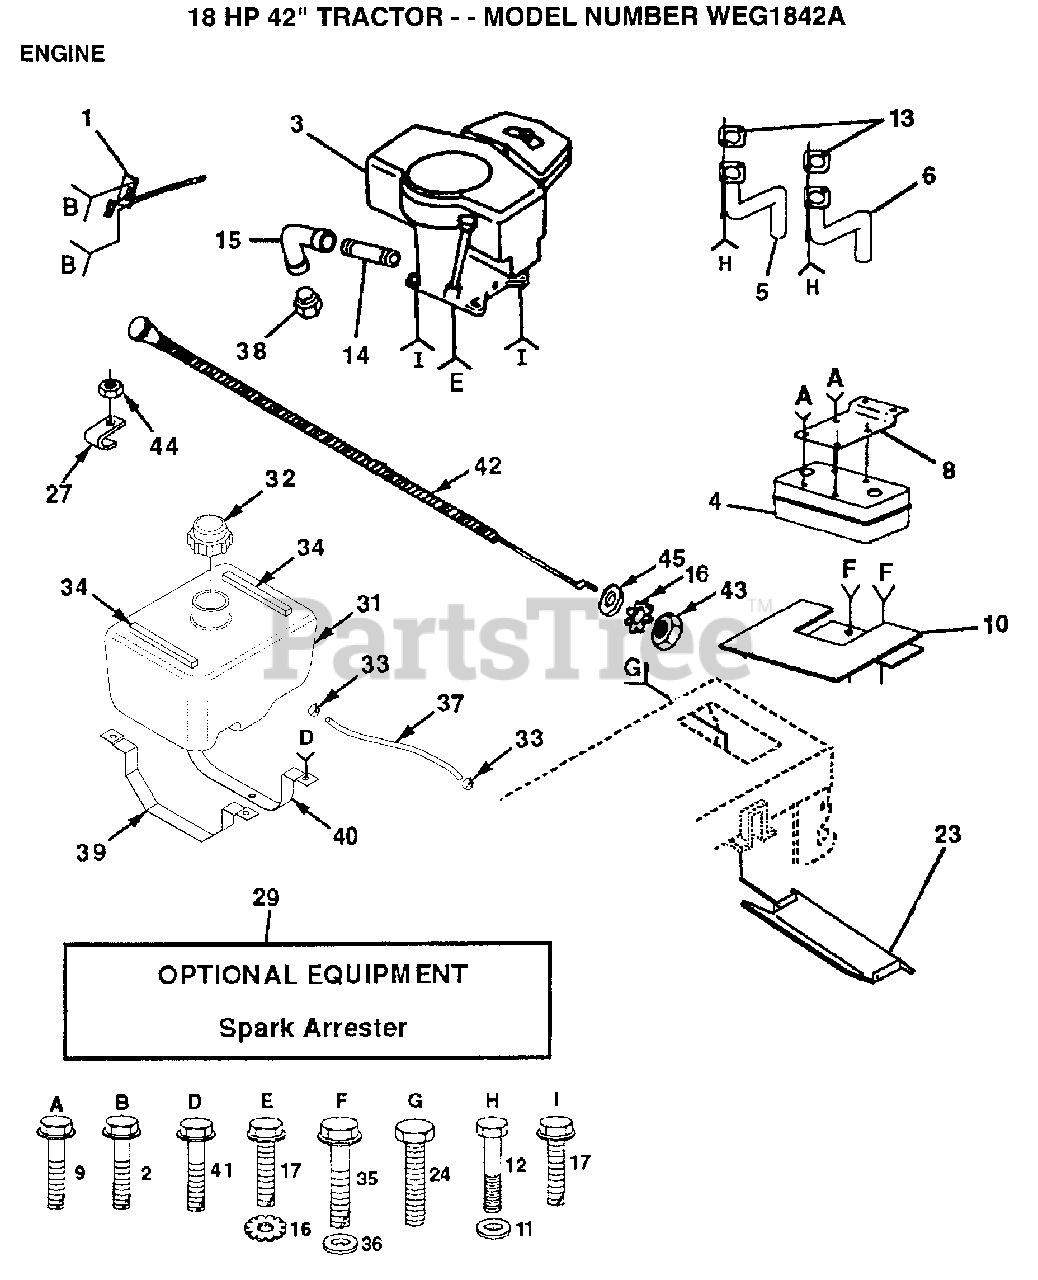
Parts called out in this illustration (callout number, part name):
2	SCREW LT
3	ENGINE B&S 18HP
5	EXHAUST ASM LH
8	BRACKET MUFFLER
9	SCREW ST
10	SHIELD HEAT LT
11	LOCKWASHER
12	EXHAUST TUBE T
14	PIPE NIPPLE LT
15	ELBOW
16	LOCKWASHER
17	SCREW LT
23	HEAT SHIELD
24	SCREW
27	CLIP T
31	TANK FUEL 1.9 NAT
32	CAP ASM FUEL
33	HOSE CLAMP
34	"STRIP,FORM"
35	SCREW
36	WASHER
37	LINE FUEL
39	STRAP TANK FUEL
40	STRAP TANK FRONT
41	SCREW
42	CHOKE CONTROL
44	NUT
45	WASHER
